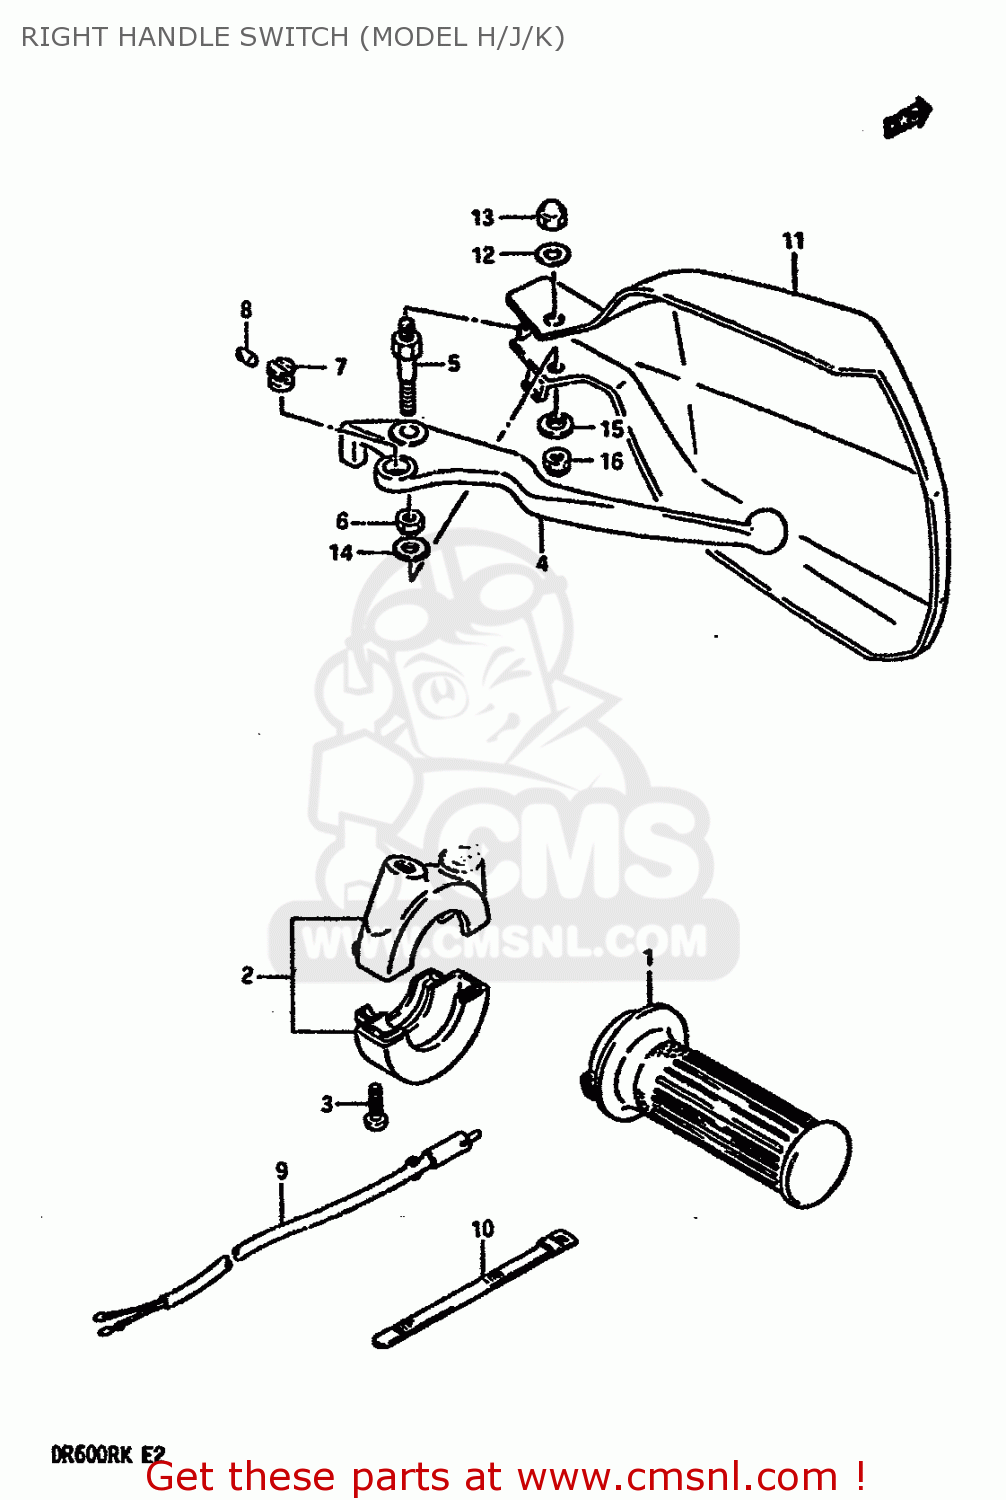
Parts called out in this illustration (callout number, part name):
1	GRIP,THROTTLE
2	CASE ASSY,THROTTLE
3	SCREW 5X20
4	LEVER,BRAKE
5	BOLT,BRAKE LEVER PIVOT
6	NUT
7	ADJUSTER
8	ROD,PUSH
9	SWITCH ASSY,STOP
10	CLAMP(L:120)
11	COVER,KNUCKLE RH (WHITE)
12	WASHER (6.5X20X1.6)
13	NUT 6MM
14	WASHER(6.5X16X1.2)
15	WASHER
16	NUT 6MM
